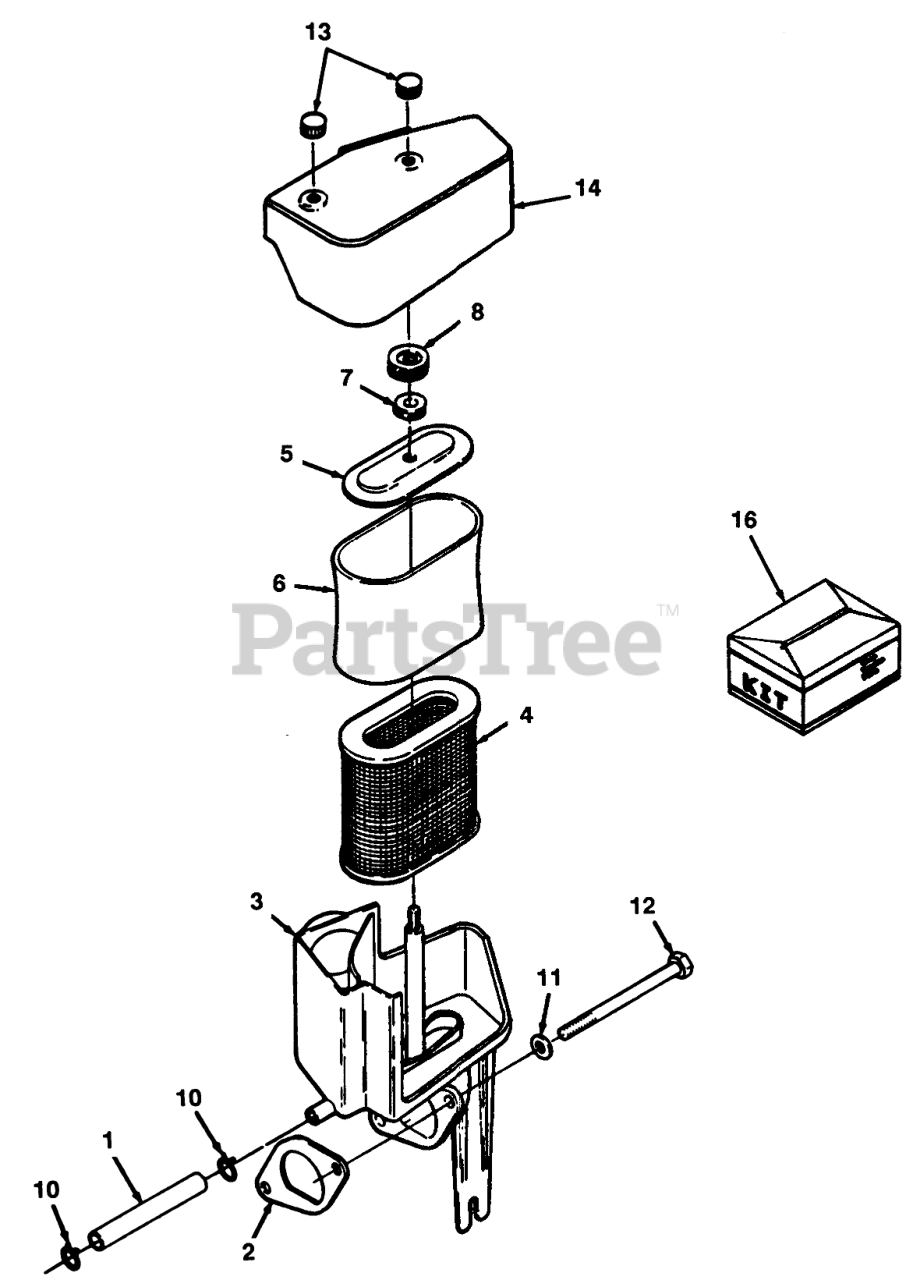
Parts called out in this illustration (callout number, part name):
1	HOSE-BRH 3/8"IDX91MM
2	Gasket
3	ADAPTER
4	AIR CLEANER ELEMENT
5	COVER-ELEMENT
6	WRAPPER-ELEMENT
7	GROMMET
10	CLAMP-HOSE
11	WASHER-FLAT
12	HHCS-M8 X 100MM
13	KNOB M6
14	COVER-AIR CLEANER
16	Kit-Air Cleaner (Incl. Ref. #2-8 & 13-15)
